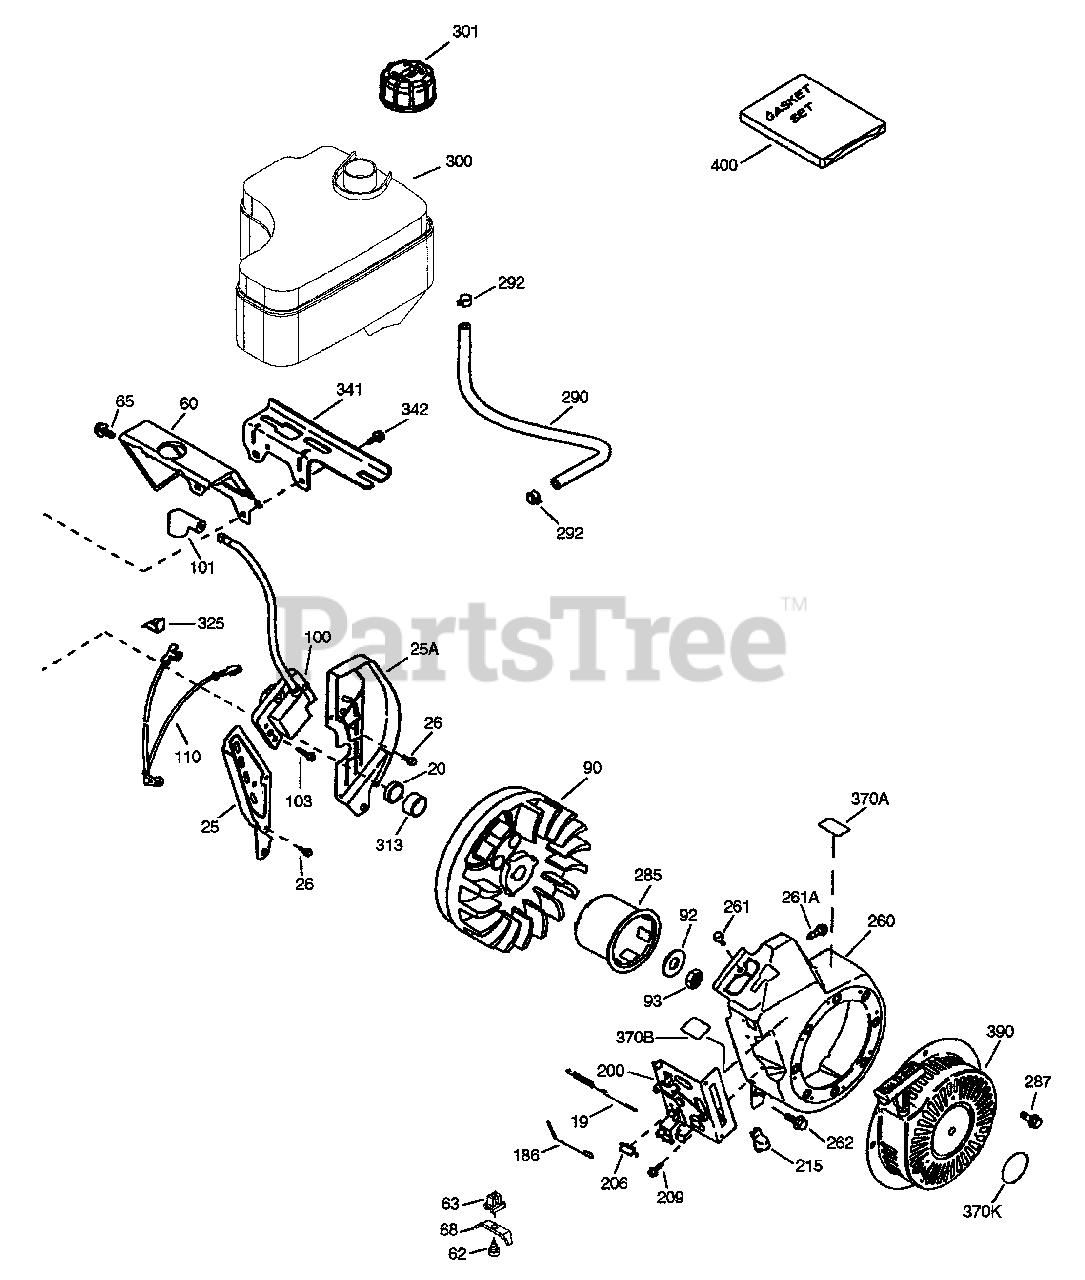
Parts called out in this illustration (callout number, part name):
19	Extension Spring
25	Air Baffle (Left)
25A	Air Baffle (Right)
26	Screw, 10-24 x 9/16"
60	Blower Housing Extension
62	Screw, 8-32 x 3/8"
65	Screw, 10-24 x 9/16"
68	Ground Terminal
92	Belleville Washer
93	Flywheel Nut
100	Solid State Ignition
101	Spark Plug Cover
103	Screw, Torx T-15, 10-24 x 15/16"
110	Ground Wire
186	Governor Link
200	Control Bracket
209	Screw, 10-32 x 1/2"
215	Control Knob
260	Blower Housing
261	Screw, 1/4-20 x 31/64"
261A	Screw, 10-32 x 1/2"
262	Screw, 1/4-20 x 31/64"
285	Starter Cup
287	Screw, 1/4-20 x 31/64"
290	Fuel Line
292	Fuel Line Clamp
300	Fuel Tank
301	Fuel Cap
325	Wire Clip
341	Fuel Tank Bracket
342	Screw, 1/4-20 x 7/8"
370A	Lubrication Decal
370B	Speed Control Decal
370K	Starter Decal
390	Rewind Starter
400	Gasket Set
